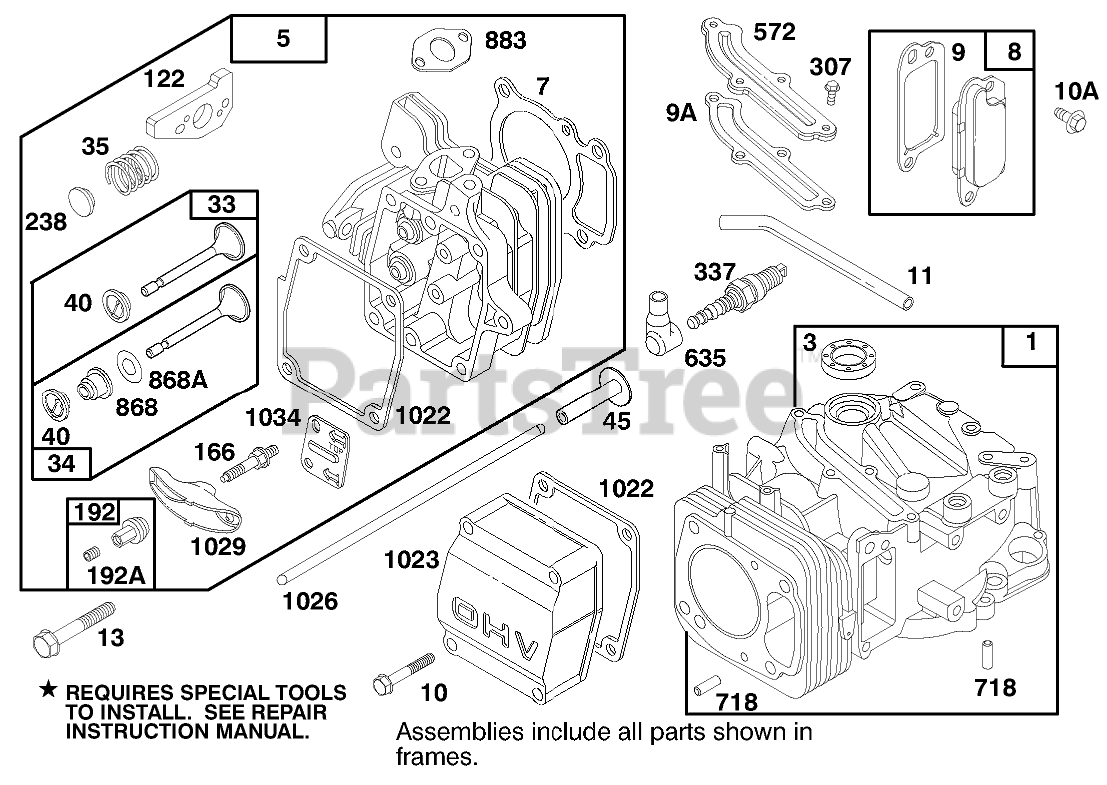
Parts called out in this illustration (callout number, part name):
1	CYLINDER ASSEMBLY
3	SEAL - OIL
5	CYLINDER HEAD
7	CYLINDER HEAD GASKET
8	BREATHER ASM
9	BREATHER GASKET
9A	GASKET-BREATHER
10	HEX HEAD SCREW
10A	HEX HEAD SCREW
11	TUBE - BREATHER
13	CYLINDER HEAD SCREW
33	EXHAUST VALVE
34	INTAKE VALVE
35	VALVE SPRING
40	SPRING RETAINER
45	VALVE TAPPET
122	ADAPTER ASSEMBLY
166	ROCKER ARM STUD
192	NUT - HEX SPECIAL
192A	Screw-Set
238	VALVE CAP
307	SCREW - SEM
337	PLUG-SPARK
572	BAFFLE - CYCLINDER
635	SPARK PLUG ELBOW
718	DOWEL - SLEEVE
868	SealAssy-Valve
868A	Seal-Valve
883	EXHAUST GASKET
1022	ROCKER COVER GASKET
1023	COVER - VALVE
1026	PUSH ROD
1029	ROCKER ARM
1034	PUSH ROD GUIDE
